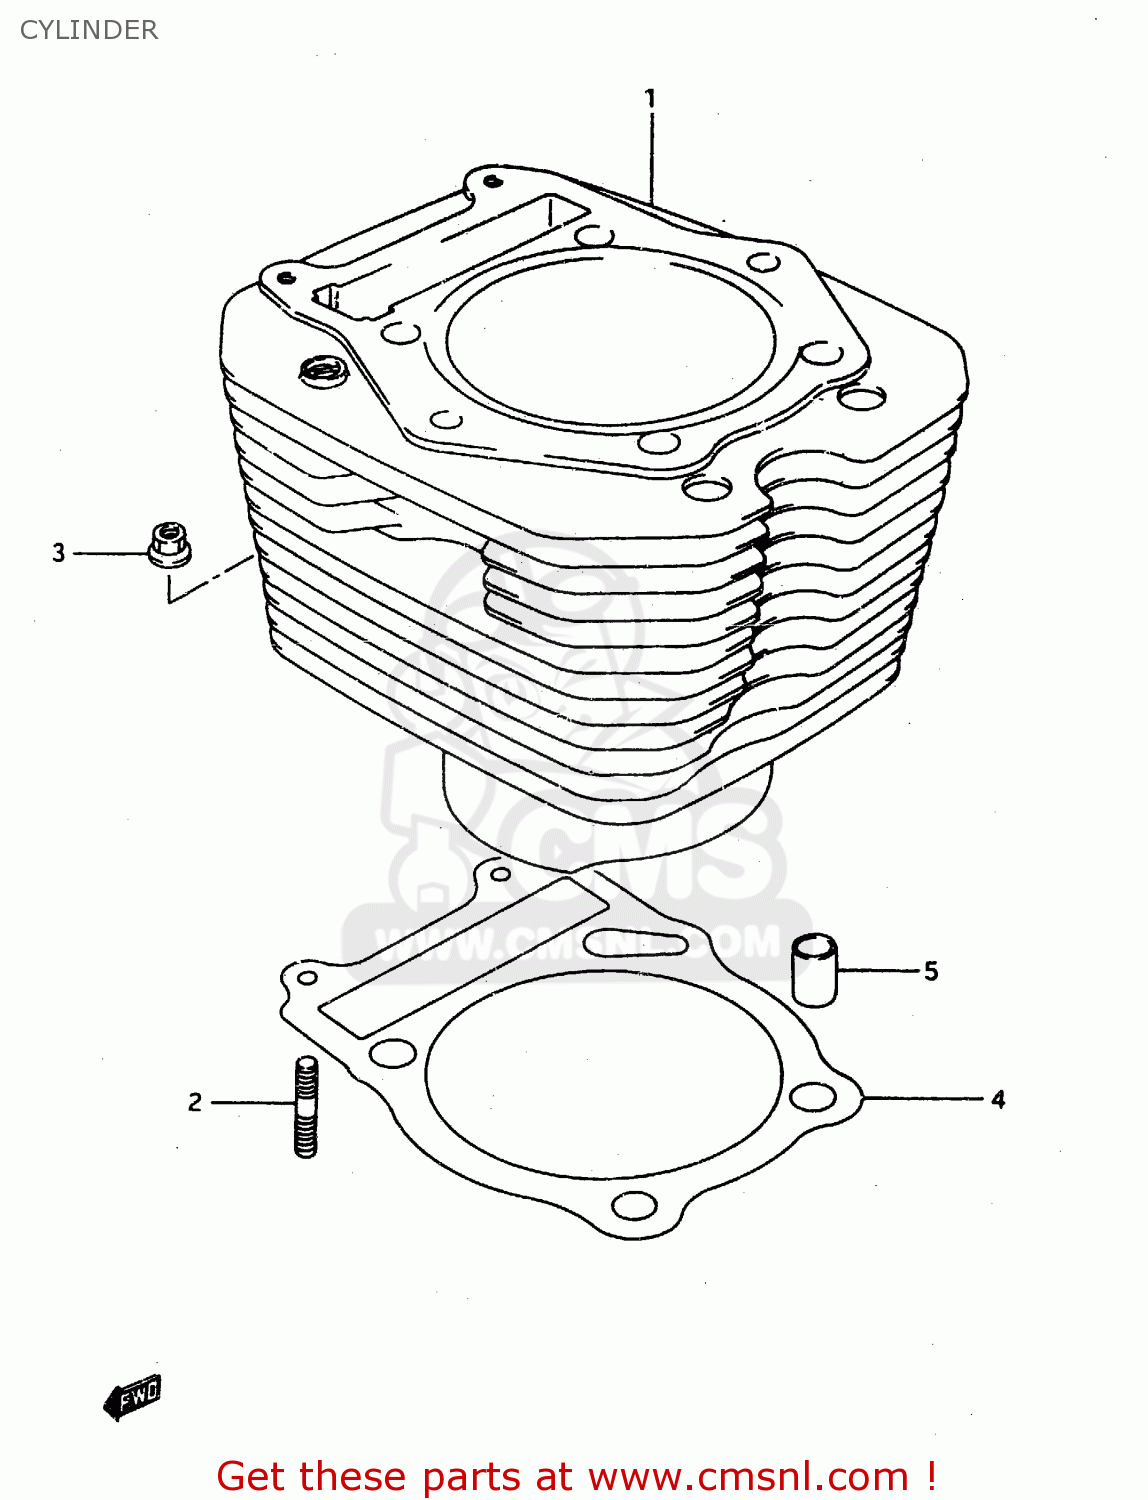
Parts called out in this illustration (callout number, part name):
1	CYLINDER
2	STUD 6X20
3	NUT
4	GASKET,CYLINDER (NAS)
5	PIN
